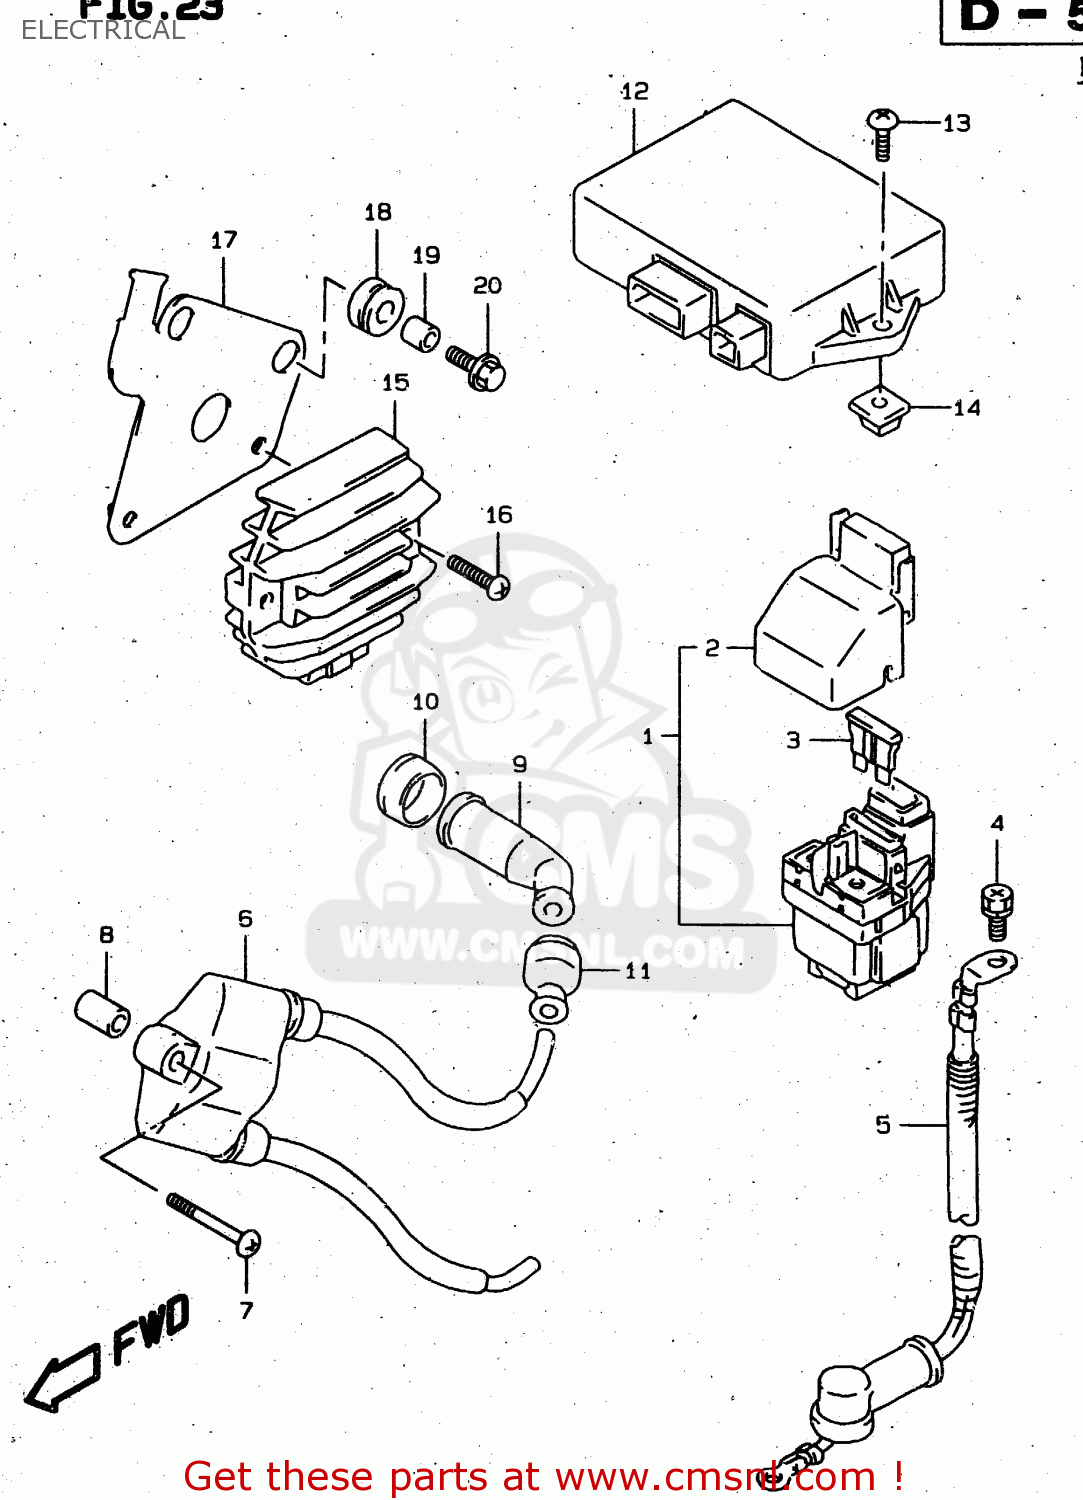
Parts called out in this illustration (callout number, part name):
1	RELAY ASSY,STARTING MOTOR
2	COVER,STARTER RELAY
3	FUSE(30A)
4	SCREW(6X8)
5	WIRE,STARTER MOTOR LEAD
6	COIL ASSY,IGNITION
7	SCREW
8	SPACER(6.5X10.5X15)
9	CAP,SPARK PLUG
10	SEAL,SPARK PLUG
11	SEAL,HIGH TENSION CORD
12	CDI UNIT
13	SCREW
14	NUT
15	RECTIFIER ASSY
16	SCREW
17	BRACKET,ELEC PARTS
18	CUSHION
19	SPACER(6.5X9X6.7)
20	BOLT
